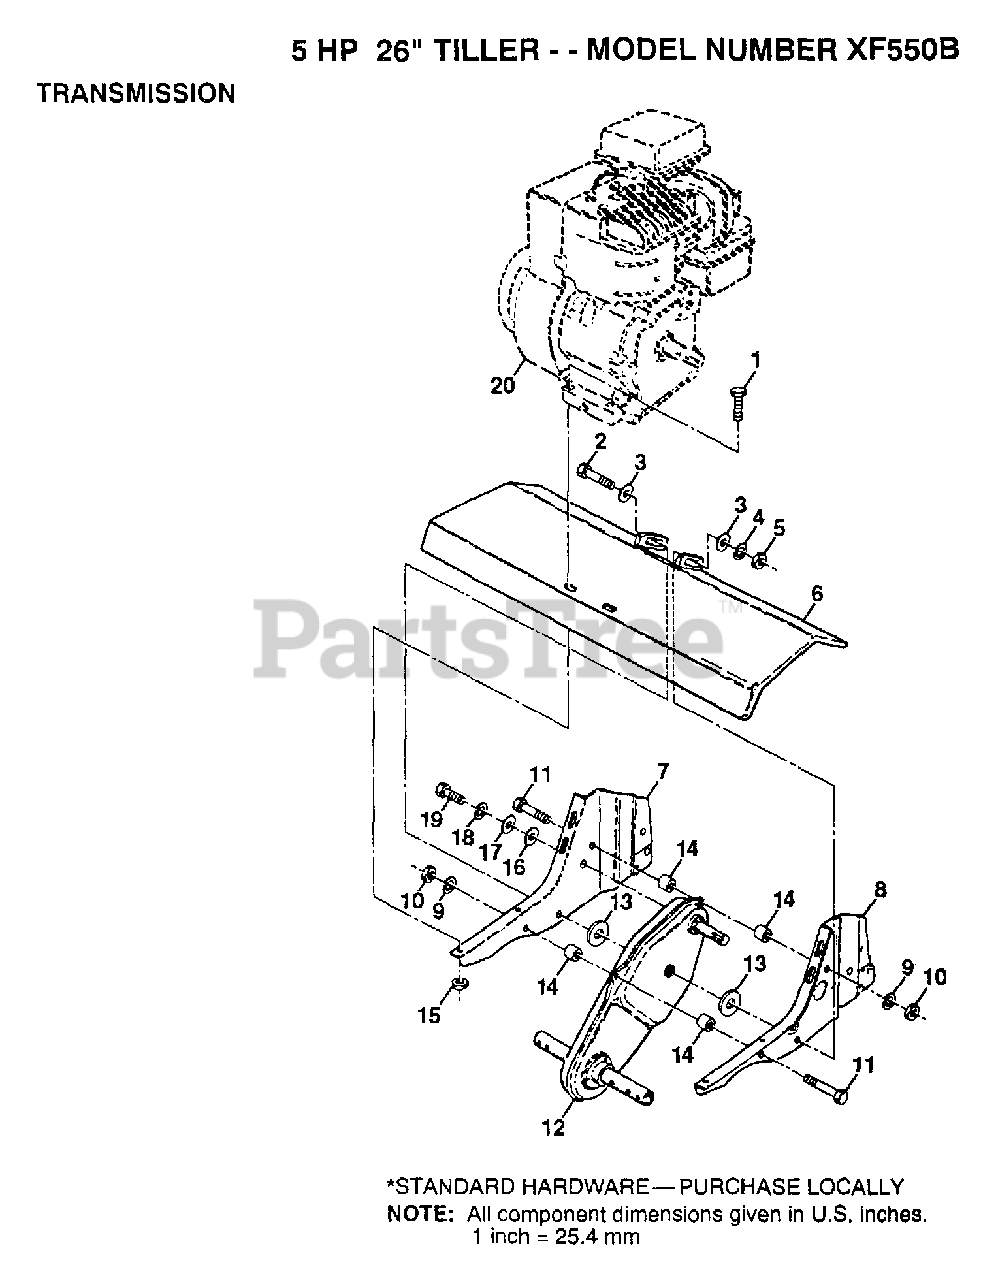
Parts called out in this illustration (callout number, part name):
1	BOLT.HEX.5/16-1.5
2	BOLT.3/8-24X3.75
3	WASHER
4	LOCKWASHER
5	GRIPCO NUT
6	"SHIELD,TINE "
8	BRACKET.ENG.LH.
9	LOCKWASHER
10	NUT.HEX.5/16-18
14	SPLIT SPACER RT
16	WASHER
17	WASHER
18	LOCKWASHER
19	BOLT
